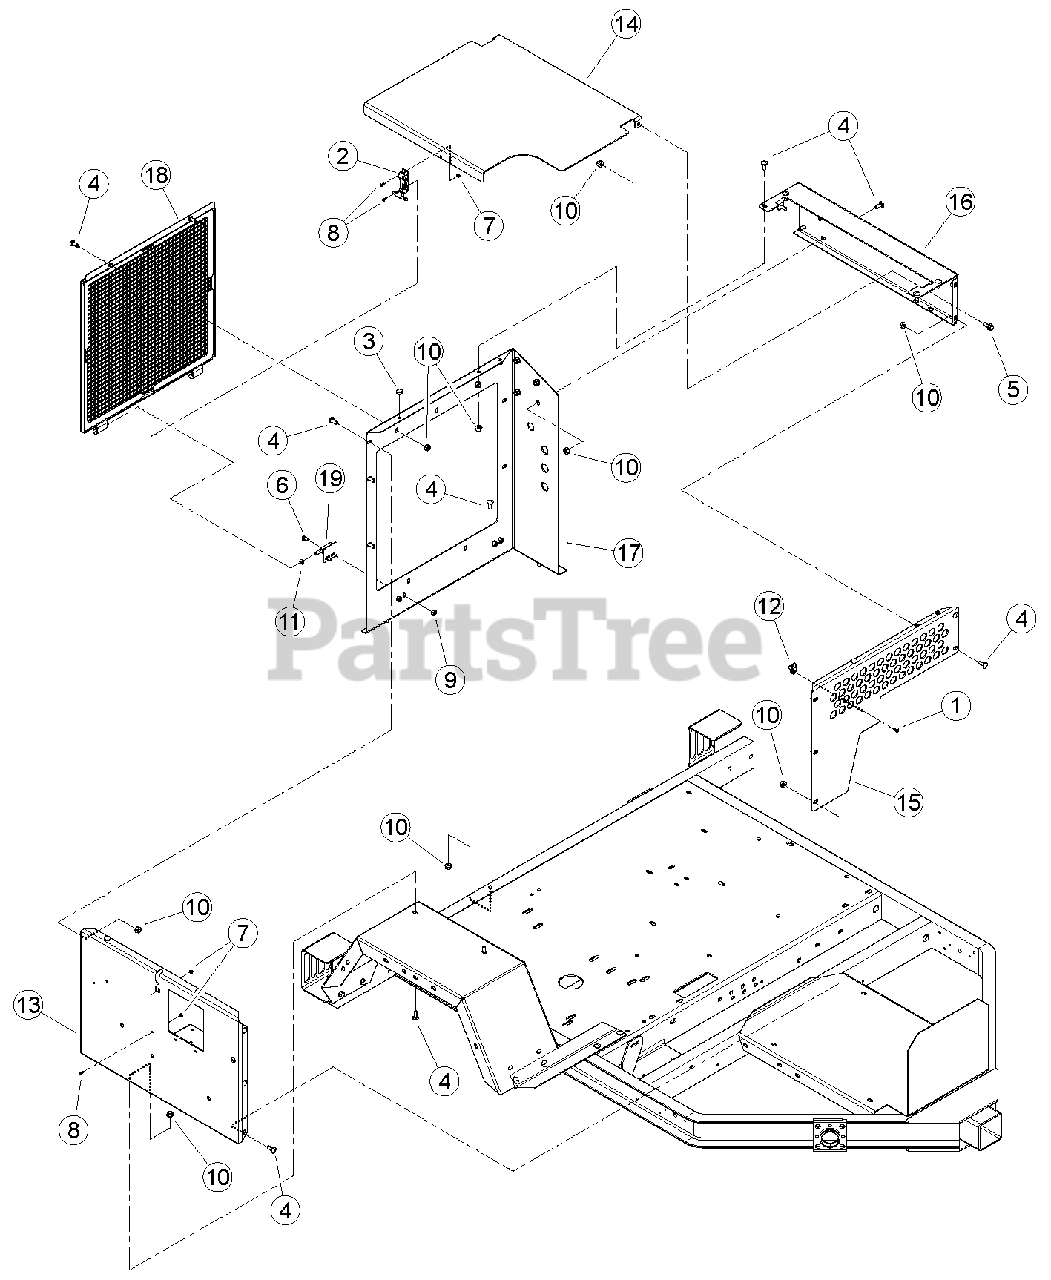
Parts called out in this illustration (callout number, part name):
1	RIVET, 1/4 X 3/4 ST POP
2	LATCH, FLEXIBLE DRAW
3	BUMPER, RUBBER
4	BOLT, 3/8 X 1" GR5 CRG NC ZP
5	BOLT, 3/8 X 1 FLANGE NC
6	BOLT, 5/16 X 3/4 GR5 CRG NC ZP
7	NUT, 10/24 NYLOCK TYPE NM ZP
8	SCREW, MCH 10-24 X 1/2"PAN HD PH ZP
9	NUT, 5/16-18 NYLOCK-FLANGE
10	NUT, 3/8-16 NYLOCK FLANGE
11	HINGE, REF 18282-00
12	CLAMP, CABLE MOUNT
13	WELDMENT, ENGINE SIDE
14	HOOD, ENGINE
15	COVER, FRONT ENGINE
16	SIDE, ENGINE COVER
17	COVER, RADIATOR
18	WELDMENT, ENGINE SCREEN
19	WELDMENT, SCREEN HINGE
